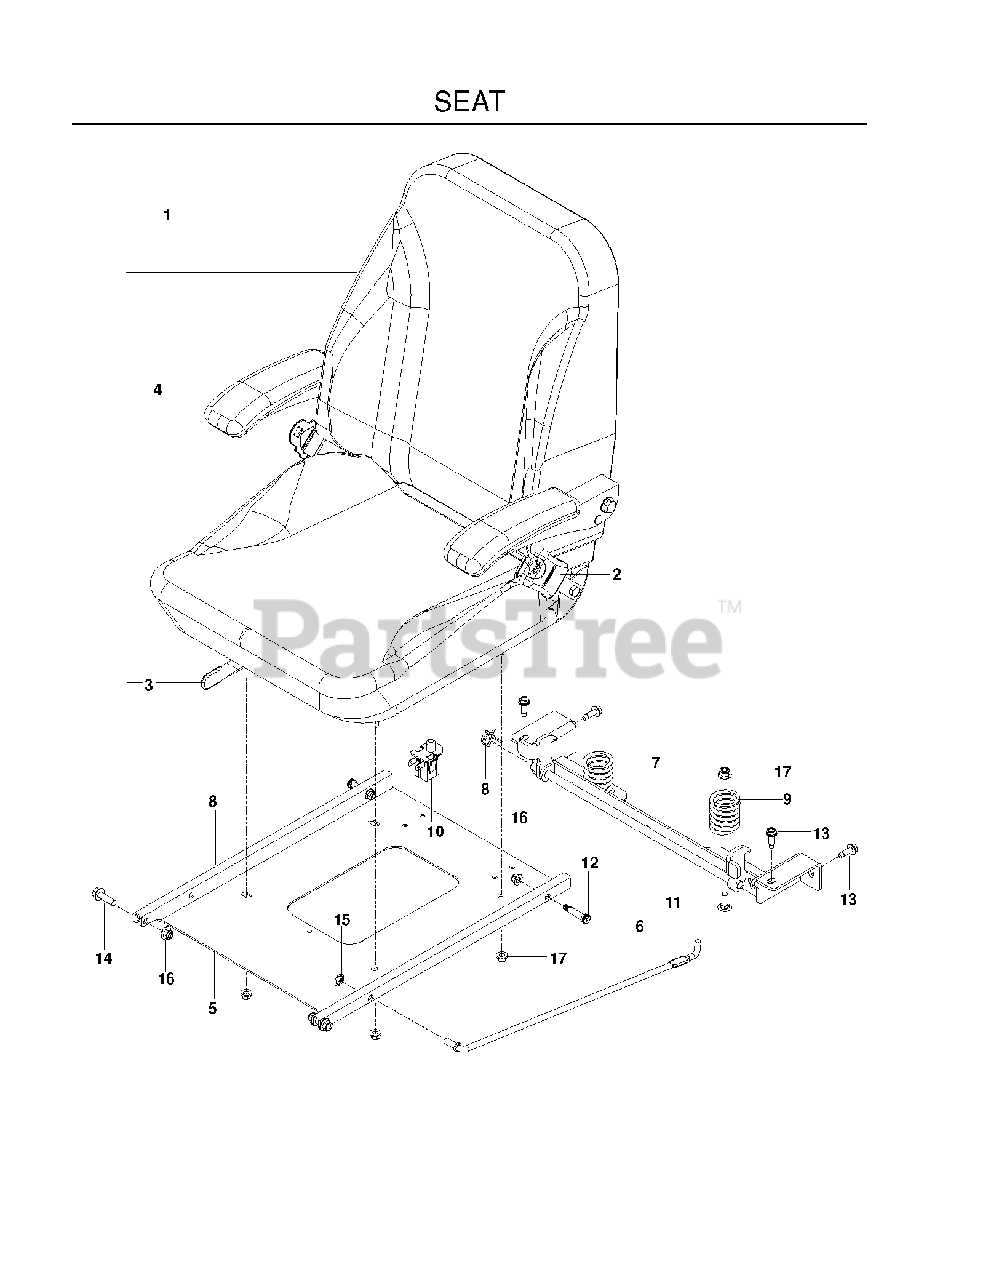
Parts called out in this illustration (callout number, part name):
1	SEAT ASSY
3	TRACK KIT
4	ARMREST, LT
5	PAN, SEAT, BLACK
6	ROD, SEAT
7	LATCH, SEAT, BLK
8	SPRING, TORSION
9	SPRING, SEAT
10	SEAT SWITCH
11	RHSNB 3/8C X 1
12	BOLT, SHOULDER 3/8 X 1.25
13	BLT 5/16-18 X 1 THRD FORM ZD
14	BOLT RETAINER 3/8
15	BOLT RETAINER 3/8
16	NUT 3/8-16 HEX FLG NYLOC ZD
17	5/16-18 NYLOC FLANGE NUT
